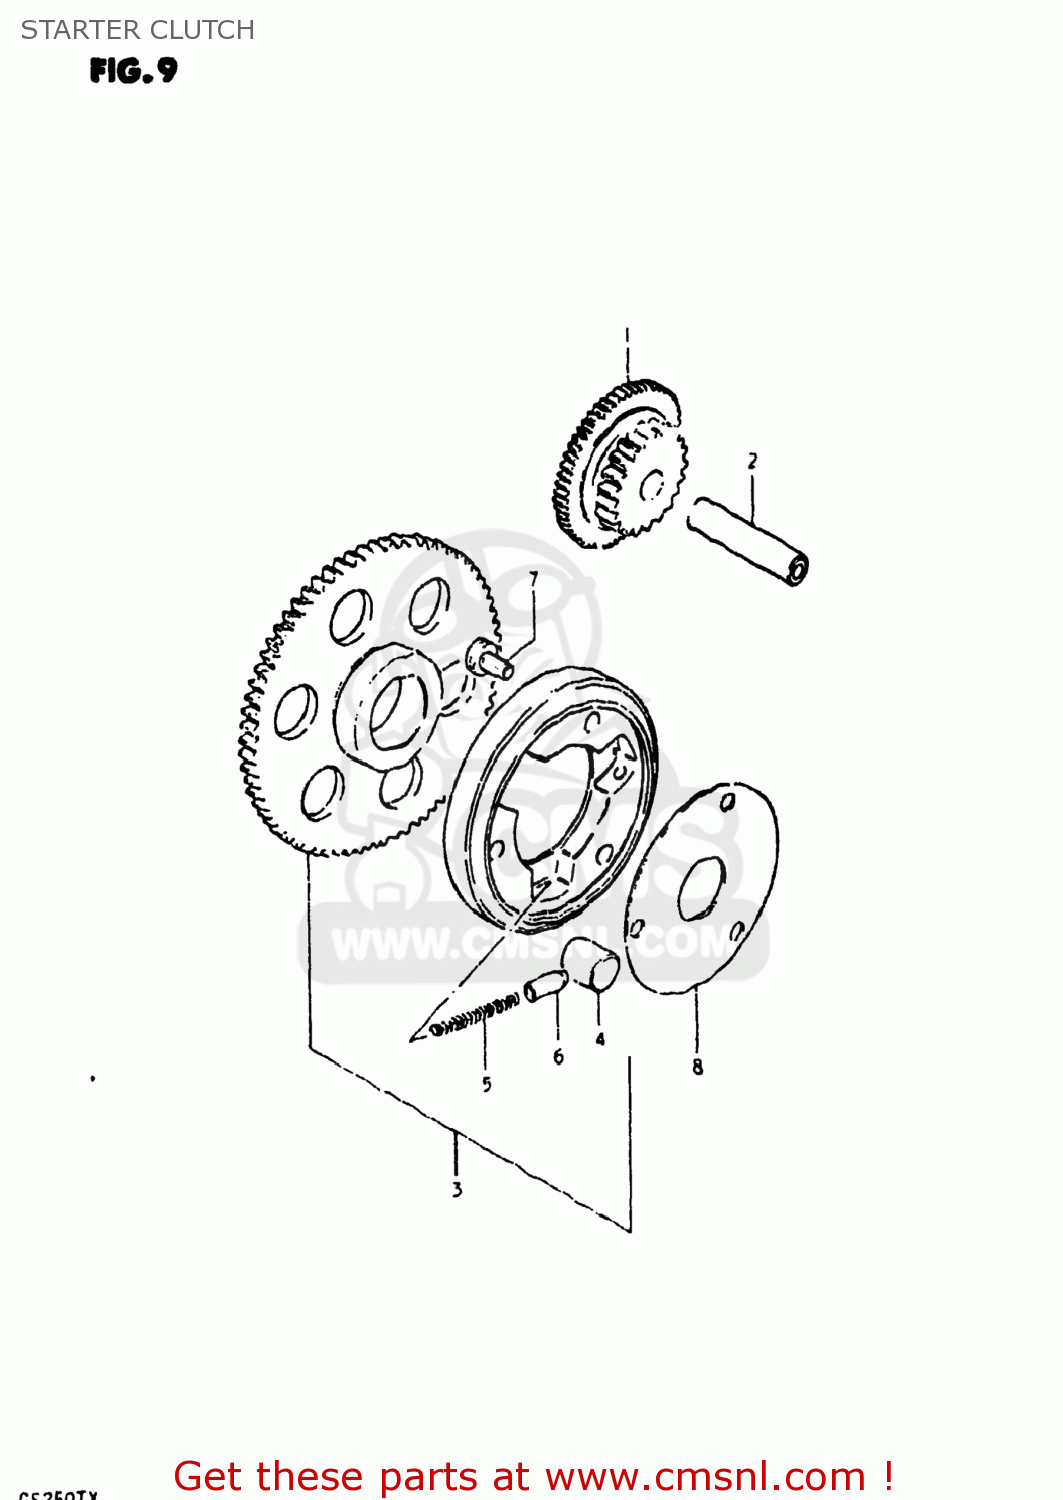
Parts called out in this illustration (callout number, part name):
1	GEAR,STARTER IDLE
2	PIN(7.4X13X40)
3	CLUTCH SET,STARTER
4	ROLLER(15X13)
5	SPRING
6	PIECE,PUSH
7	BOLT
8	SHIM,STARTER CLUTCH HUB
